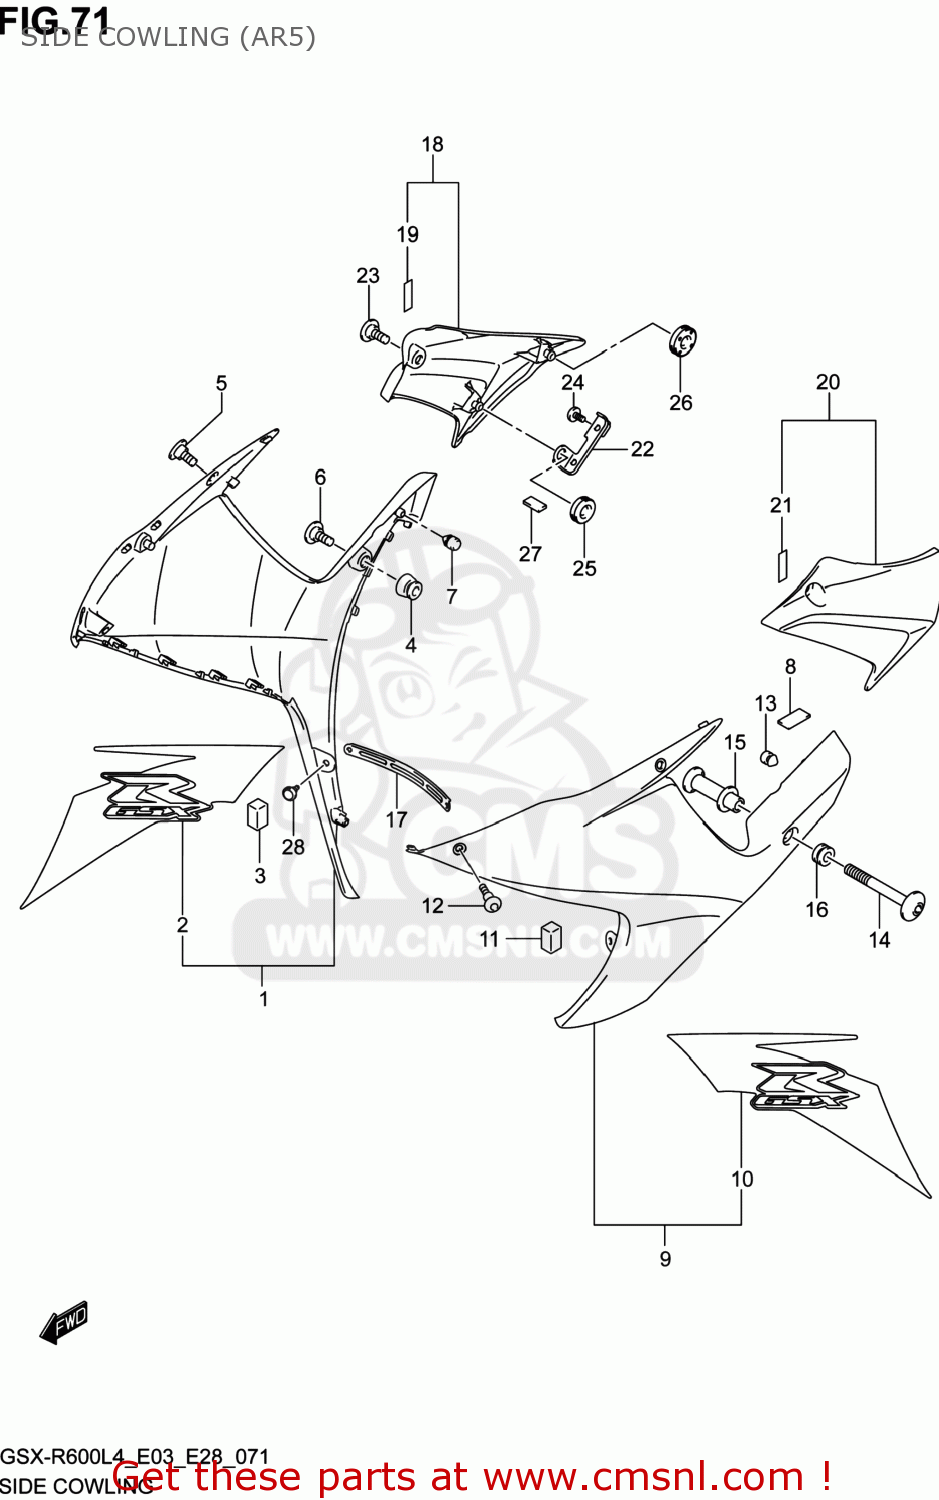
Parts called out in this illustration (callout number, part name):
1	COWLING,SIDE,R(BLACK)
2	TAPE,SIDE COWLING,R
3	CUSHION,SIDE COWL FR
4	CUSHION,UNDER COWLING,L
5	SCREW(5X13)
6	BOLT(6X20)
7	CUSHION
8	CUSHION,FUEL TANK NO.2
9	COWLING,SIDE,L(BLACK)
10	TAPE,SIDE COWLING,L
11	CUSHION,SIDE COWL FR
12	SCREW(5X13)
13	CUSHION
14	SCREW,SIDE COWL,L
15	SPACER,SIDE COWL,L
16	CUSHION
17	PLATE,UNDER COWL CTR
18	COVER,SIDE COWLING,R
19	TAPE(6X25X0.13)
20	COVER,SIDE COWLING,L
21	TAPE(6X25X0.13)
22	BRACKET,COVER SIDE,R
23	SCREW(5X13)
24	SCREW(6X12)
25	CUSHION
26	CUSHION
27	CUSHION
28	CLIP
